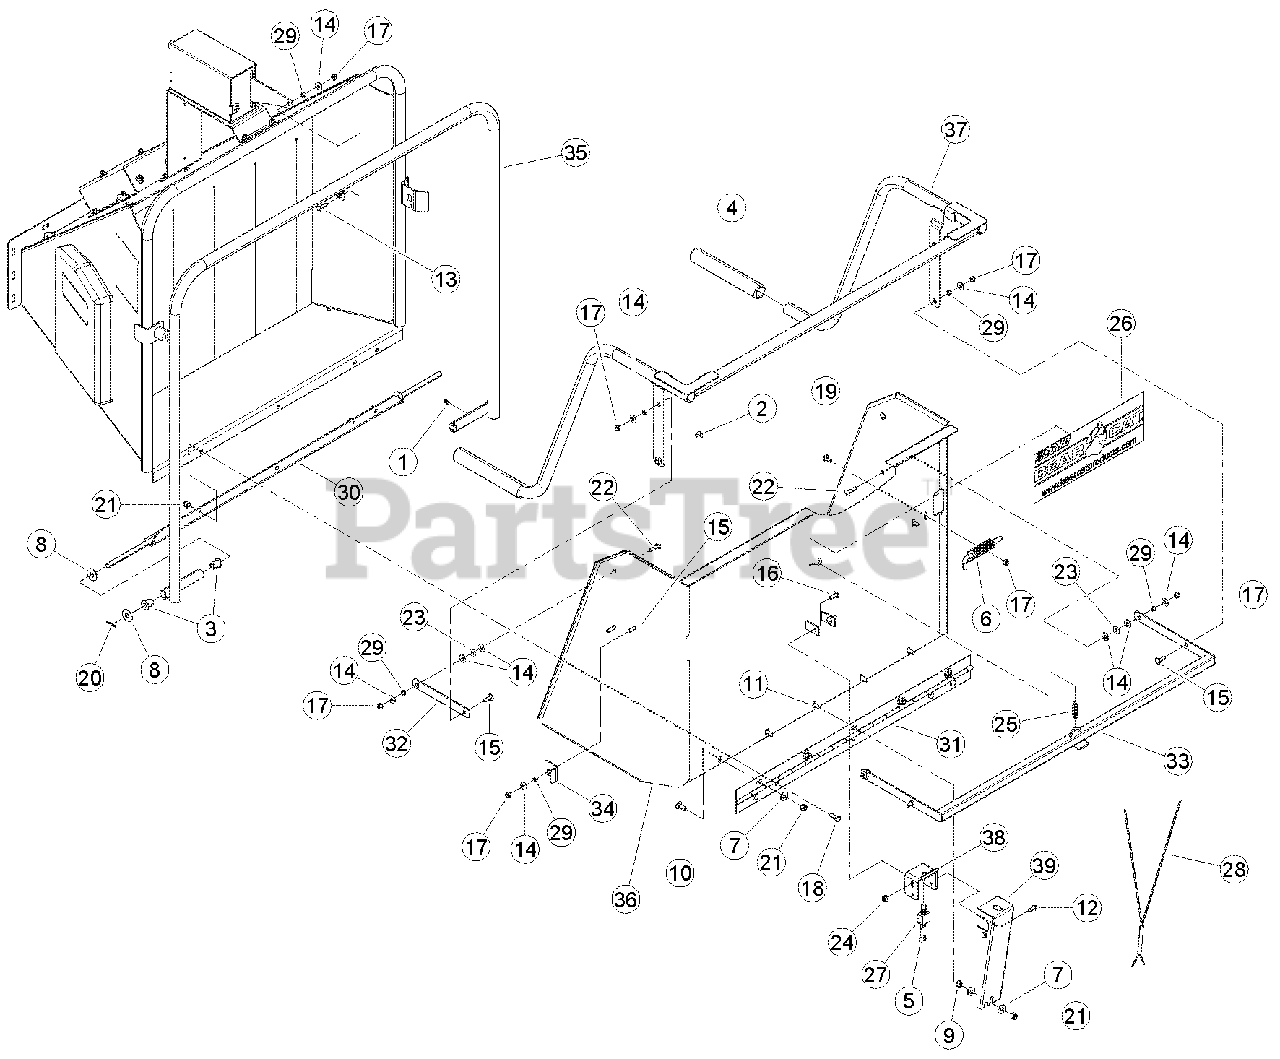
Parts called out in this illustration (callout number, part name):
1	FITTING, 1/4 SELF-TAP GREASE
2	BUMPER, RUBBER
3	BUSHING, 1/2 X 1 FLANGE LUBE
4	GRIP, 1.219 X 10.00
5	CONNECTOR, 1/4 QD MALE
6	LATCH, RH HINGE
7	WASHER, 3/8 FLAT ZP
8	WASHER, 1/2 FLAT ZP
9	NUT, 3/8 SERR FLANGE NC ZP
10	BOLT, 3/8 X 1 CRG GR5 NC ZP
11	BOLT, 3/8 X 1-1/2 CRG GR5 NC ZP
12	SCREW, 11/32 X 7/8 HWH AB THREAD ZP
13	BOLT, 5/16 X 1 HEX HD GR5 NC ZP
14	WASHER, 5/16 FLAT ZP
15	BOLT, 5/16 X 1 CRG GR5 ZP
16	BOLT, 5/16 X 7/8 CRG GR5 NC ZP
17	NUT, 5/16 NE NYLOCK ZP
18	BOLT, 3/8 X 1-1/4 HEX HD GR5 ZP
19	BOLT, 5/16 X 3/4 CRG GR5 NC ZP
20	PIN, 1/8 X 1.00 COTTER ZP
21	NUT, 3/8 NE NYLOCK ZP
22	BOLT, 5/16 X 1-1/4 CRG GR5 ZP
23	WASHER, 5/16 ID X 7/8 OD NYLON FLAT
24	NUT, 5/16-18 NYLOCK-FLANGE
25	SPRING, 1/2 X 2.00 LONG ZP
26	DECAL, BEARCAT WEB
27	SWITCH, MOMENTARY IP67 NORMALLY ON
28	HARNESS, SAFETY BAR
29	SPACER, IDLER PIVOT
30	WELDMENT, CONTROL PIVOT
31	HINGE, EXTENSION TRAY
32	LINK, PARALLEL
33	WELDMENT, KNEEBAR PIVOT
34	LOCK, SAFETY BAR
35	WELDMENT, CONTROL ARM
36	WELDMENT, EXTENSION TRAY W/ TABS
37	WELDMENT, KNEEBAR
38	BRACKET, SWITCH
39	SHIELD, SAFETYBAR SWITCH
